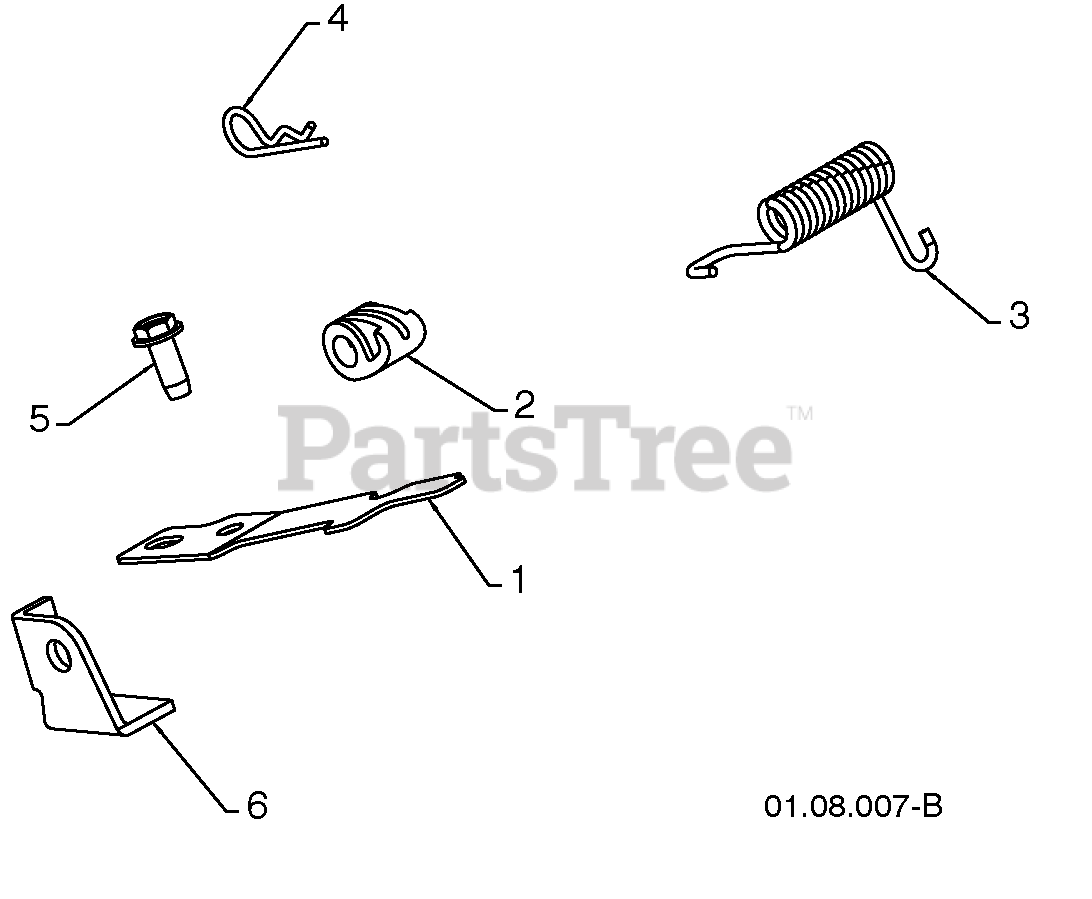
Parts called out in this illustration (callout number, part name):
1	INTERLOCK SPRING
2	INTERLOCK CAM
3	TORSION SPRING
4	RETAINER
5	SCREW 1/4-20 X .625
6	INTERLOCK STOP
